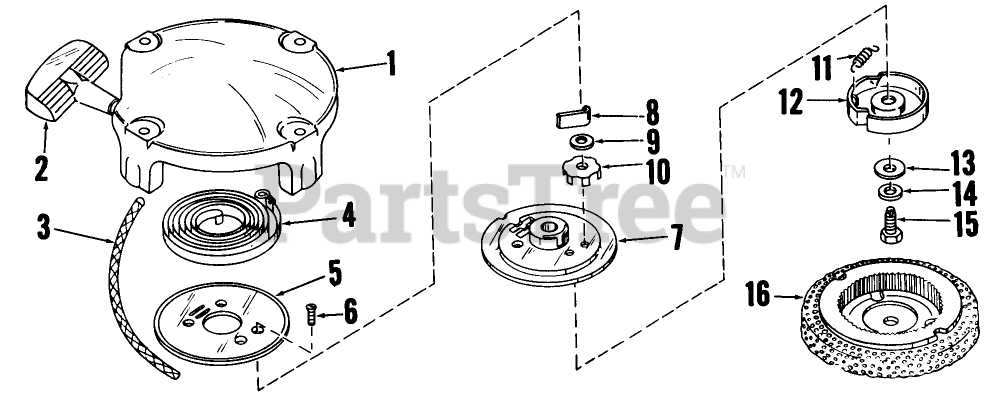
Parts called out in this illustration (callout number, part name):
1	Housing, Starter
2	Assy., Starter
3	Rope, Starter
4	Spring, Rewind
5	Pulley, Sheave
6	Screw
7	Hub, Pulley
8	Dog-Starter
9	Washer, Thrust
10	Brake
11	Spring, Retainer
12	Retainer
13	Washer, Spacer
14	Washer, Brake
15	Screw
16	Hub Screen
